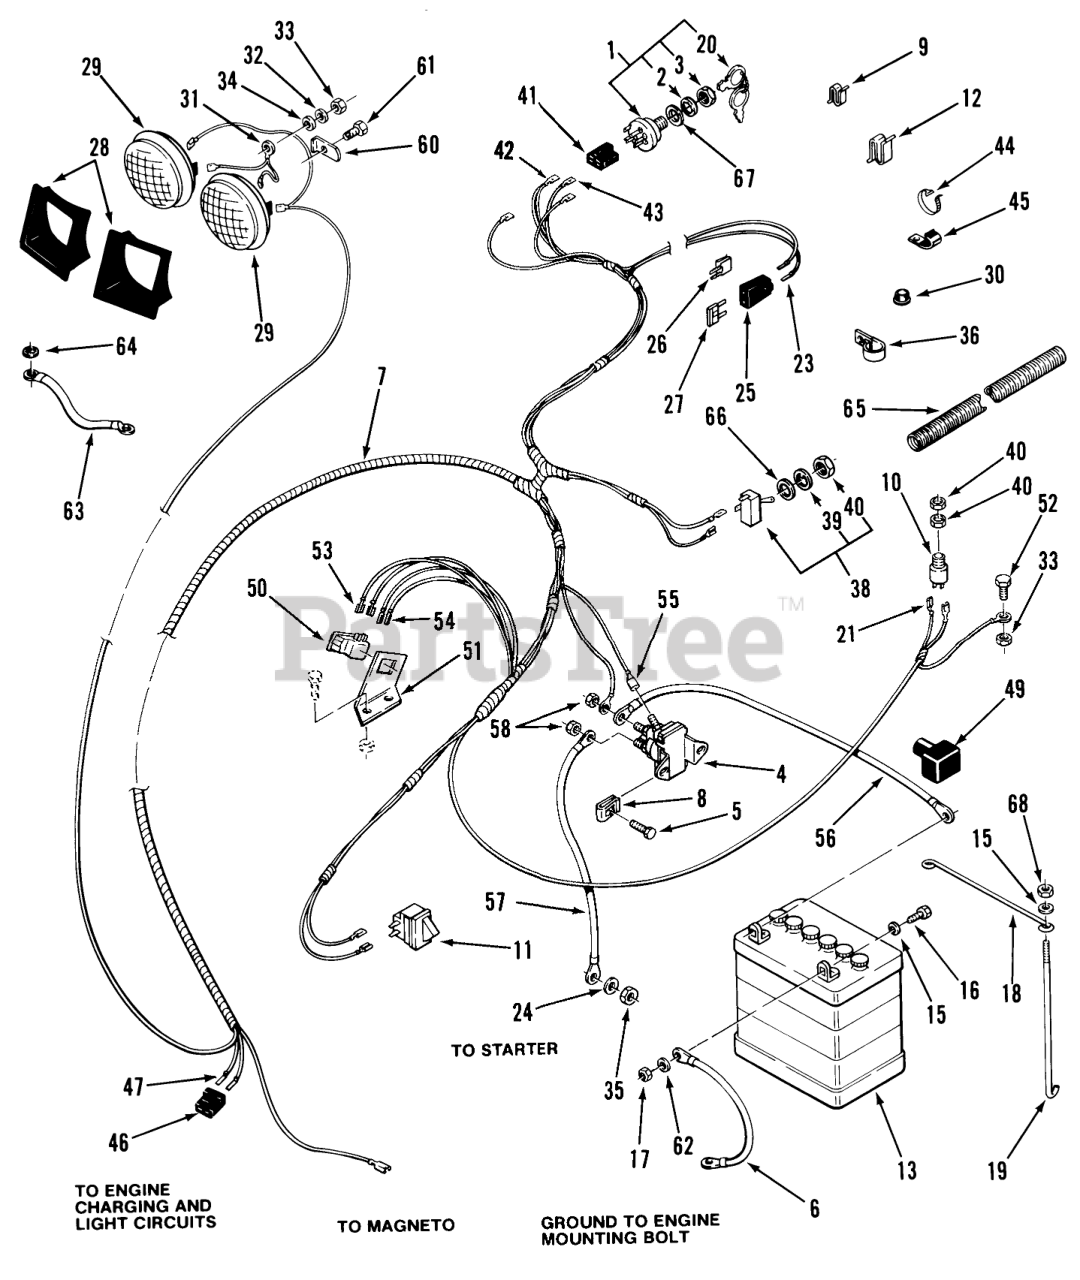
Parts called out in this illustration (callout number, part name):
1	ASSY-SWITCH IGNITION
2	LOCKWASHER
4	Solenoid
5	Screw
6	Wire
7	Wiring Harness Assy 216-5 Only
7	Wiring Harness Assy B-115 Only
7	HARNESS-WIRING
8	Speed Nut
9	SPEED CLIP
10	SWITCH-SEAT
10	SWITCH-BALL
11	SWITCH INTERLOCK
12	CLIP-CABLE
13	Battery
16	Bolt
17	Nut
18	ROD-HOLD DOWN
20	Key-EL
21	Connector
23	TERMINAL-FUSE
24	Washer
25	AUTO-FUSEBLOCK TERM
27	FUSE-BLADE, 15 AMP
28	HEADLIGHT BEZEL ASSY.(SERVICE)
29	HEADLAMP
30	BUSHING-NYLON .75
31	LIGHT GROUND WIRE
32	WASHER 5/16 SAE
33	Nut
34	Washer-Lock
35	Nut
36	CLAMP
38	SWITCH-LIGHTS
39	TAB-WASHER
40	NUT-HEX, SPECIAL
41	CONNECTOR-5 WAY-SERV
42	TERMINAL-TAB RCPT
43	Terminal
44	Cable Tie
45	CLIP
46	Conn Body Part of 7
47	Terminal
49	Boot
50	PTO Interlock Switch
51	BRACKET-SWITCH R
52	Bolt
53	Terminal
54	Wire Terminal (Part of 1)
55	Terminal Part of 5
56	Wire
57	Starter To Solenoid Cable 23.0 in. (58.4 cm) B-115 Only
57	Starter To Solenoid Cable 16.0 in. (40.6 cm) 216-5 Only
58	Nut
60	LOCK-HEADLIGHT
61	Bolt
62	Washer
63	WIRE GROUND
64	Washer-Lock
65	Conduit 216-5 Only
66	Washer
67	Washer
68	Nut
